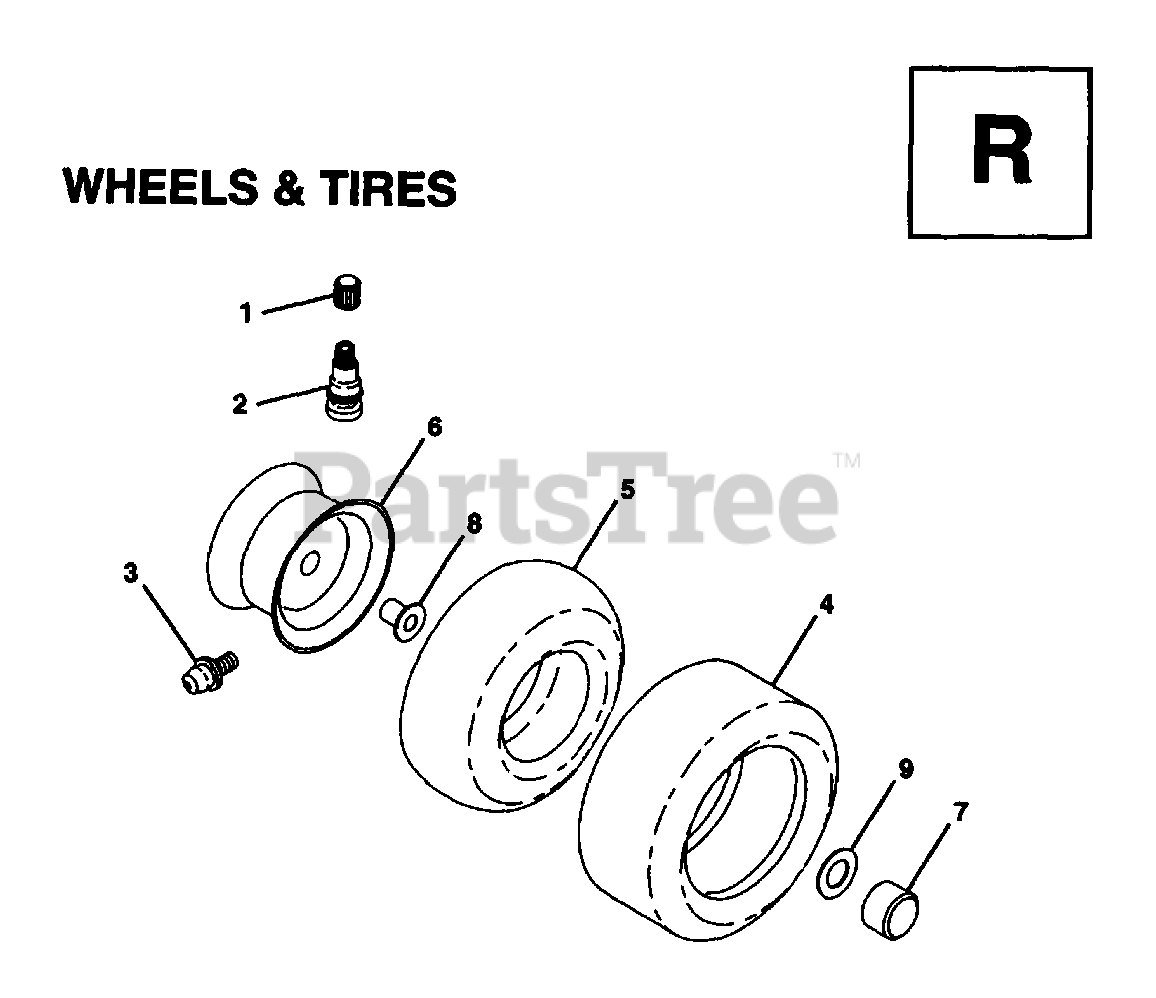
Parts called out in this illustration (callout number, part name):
2	VALVE STEM LT
3	FITTING LT
4	TIRE FRONT 15X6-6
5	TUBE.16X6.5/7.5-8
5	TUBE.5.3/4.5/6
6	FRONT RIM
6	RIM ASM REAR 8"
7	CAP.HUB.FRONT.LT.BLACK
8	BEARING T
